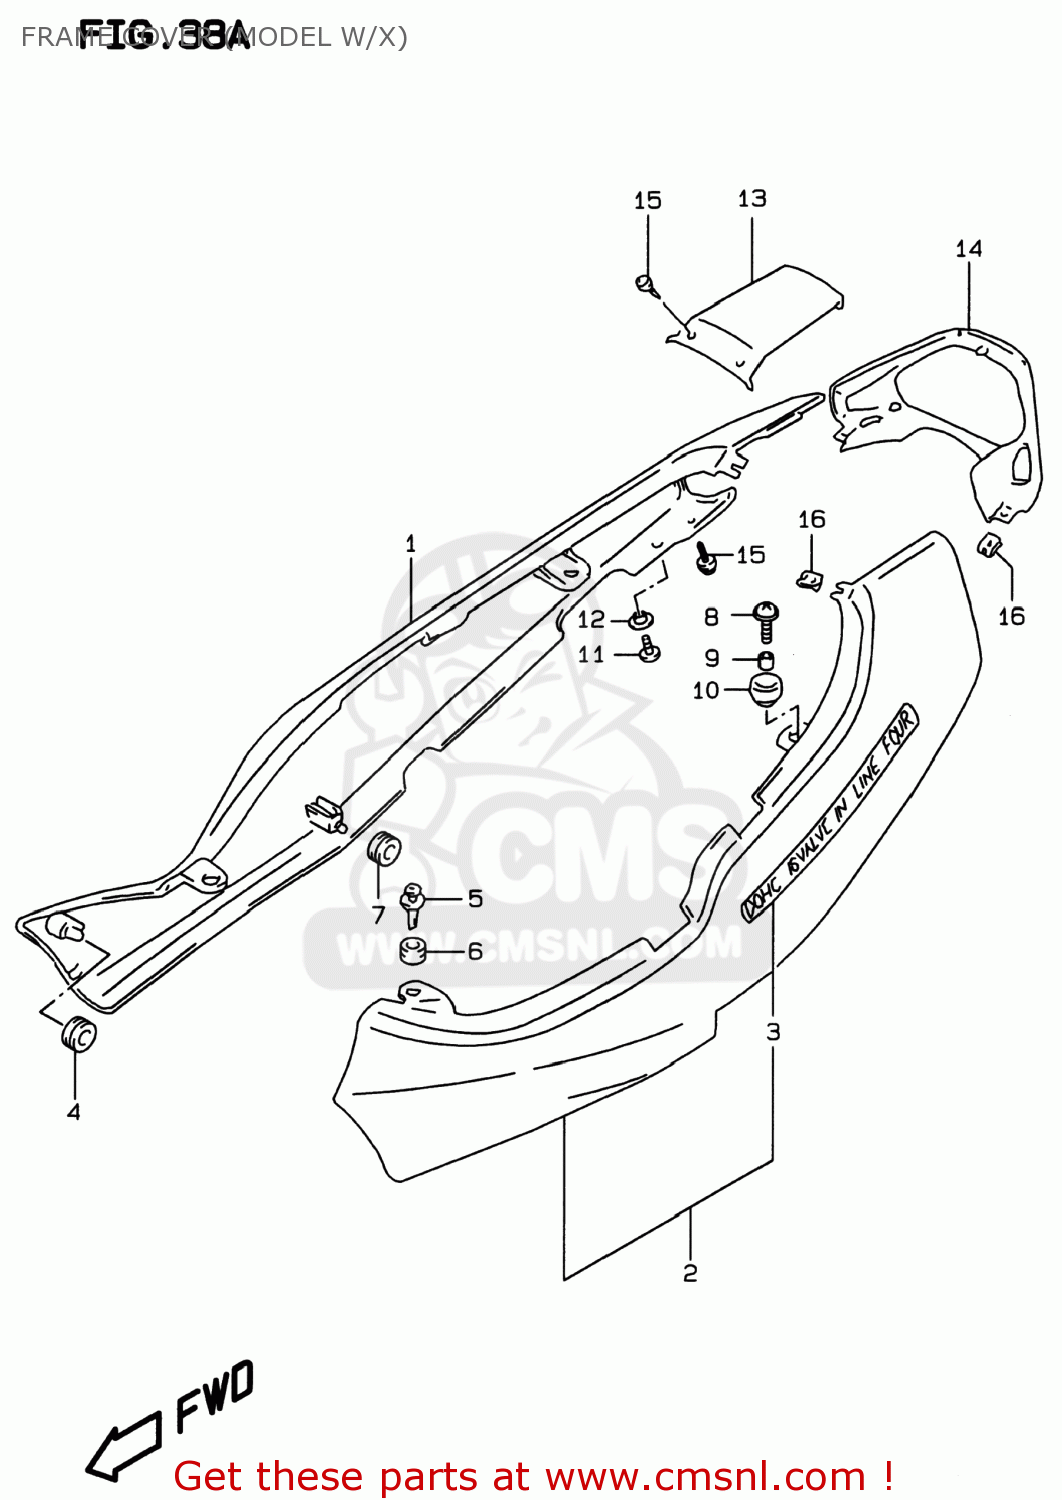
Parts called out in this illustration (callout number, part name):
1	COVER,FRAME,R(ORANGE)
2	COVER,FRAME,L(BLUE)
3	EMBLEM,FRAME COVER
4	CUSHION,FRAME COVER FR
5	CLIP
6	CUSHION
7	CUSHION
8	SCREW(6X20)
9	SPACER(6.5X10X9.4)
10	CUSHION
11	SCREW
12	WASHER(6.3X16X1.5)
13	COVER,FRAME,CENTER
14	COVER,FRAME RR
15	SCREW
16	NUT
